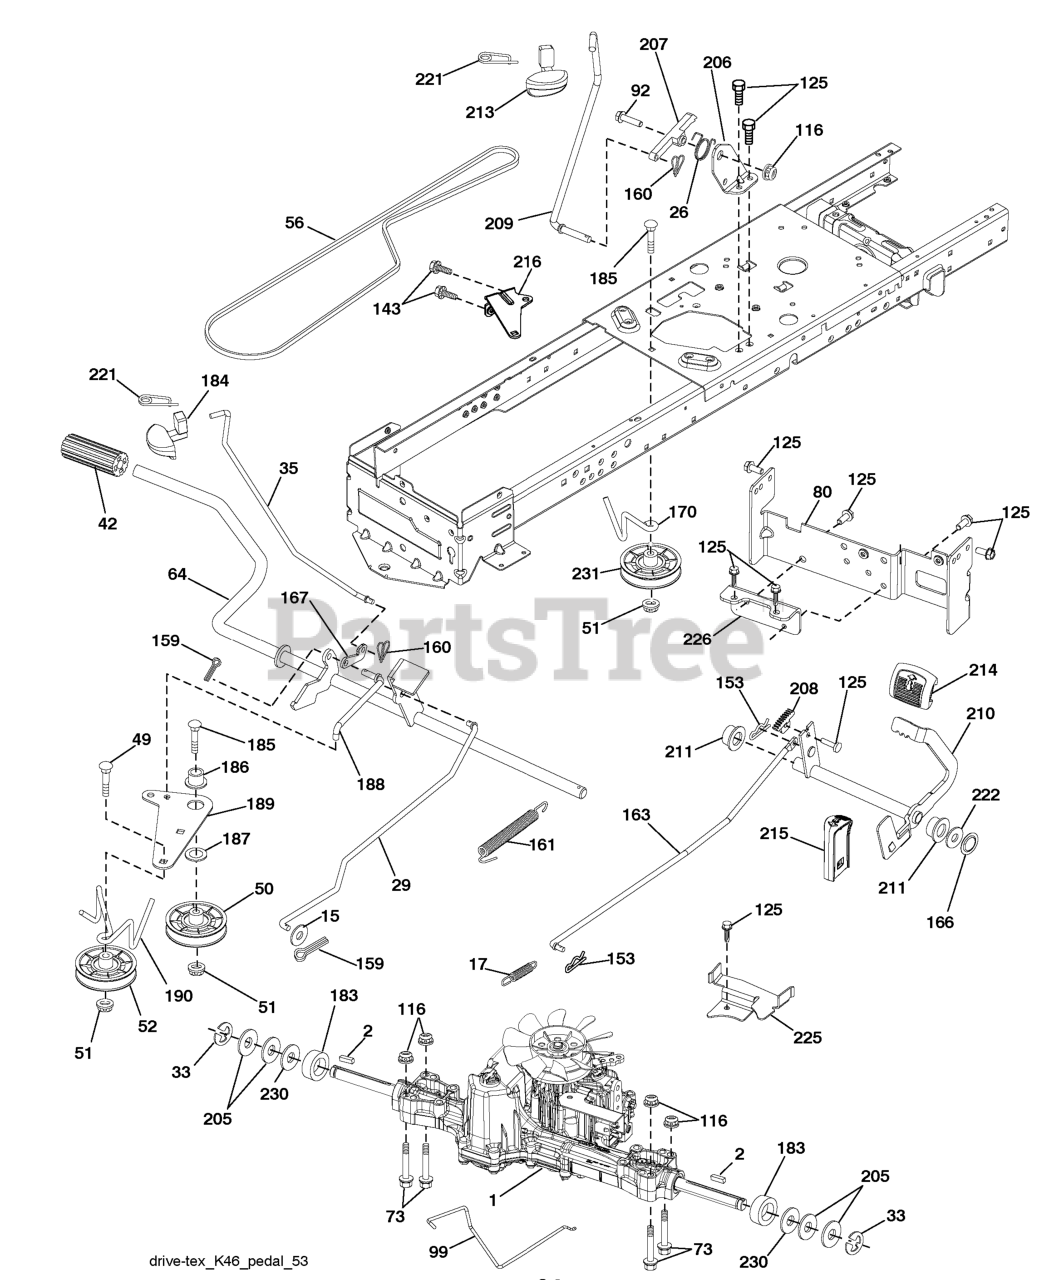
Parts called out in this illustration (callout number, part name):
1	Transaxle, Tufftorq K46 Bt (See Transaxle Breakdown)
2	SQUARE KEY
15	WASHER
17	SPRING.BRAKE.K46.GREEN
26	SPRING.RETURN.CRUISE
29	ROD.BRAKE.K46
35	ROD.BRAKE.PARKING.GT.H
42	PEDAL COVER T
50	IDLER.FLAT.910.OFFSET
51	NUT LOCK FLG 3/8-16 UNC
52	IDLER.V-GROOVE.910.OFFSET
56	V-BELT.MOWER.92.40.42/K46
64	SHAFT.ASM.PEDAL.BRK.CNTR
73	BOLT HEX 5/16-18 GR 5
80	STRAP TORQUE
92	BOLT
99	ROD.SPRING.BYPASS.K46.LT.Z
116	NUT LOCK HEX FLANGE 5/16-18
125	SCREW
143	Screw 5/16-18 X 1/2
153	RETAINER M
159	COTTER PIN
160	RETAINER CLIP
161	SPRING, RETURN LT
163	ROD.CONTROL.PEDAL.K46
166	NUT.PUSH.625
167	LATCH.BRAKE.SPRING
170	KEEPER.CENTER SPAN.1.688
183	SPACER AXLE
184	HANDLE.PARKG.BRK.HUSQ X667
186	SPACER.RETAINER
187	WASHER 12/32X2X10GA
188	RP.LINK.CLUTCH.GROUND.DRIVE
189	BELLCRANK.GROUND.DRIVE.TEX.
190	KEEPER.BELLCRANK.DRIVE
206	BRKT.MOUNT.LATCH.CRUIS
207	LATCH.CONTROL.CRUISE
208	GEAR.SECTOR.CONTROL.CR
209	ROD.CONTROL.CRUISE.GT.
210	ROCKER.ASM.PEDAL.CONTR
211	BEARING.NYLON
213	KNOB.CONTROL.CRUSIE.HU
214	PEDAL.FORWARD.PAD.TEX
215	PEDAL.REVERSE.TEX.GT.4
216	BRACKET.PULLEY.IDLER.W/TEX
221	RETAINER.SPRING.CLIP.H
222	WASHER 21/32 X 1-1/4 X 10 GA.
225	KEEPER.BELT.TRANSAXLE.K46
226	BRACKET.MOUNT.TORQUE.K46.TLT
230	WASHER.HARDENED
231	IDLER.V-GROOVE.1.688.OFFSET
